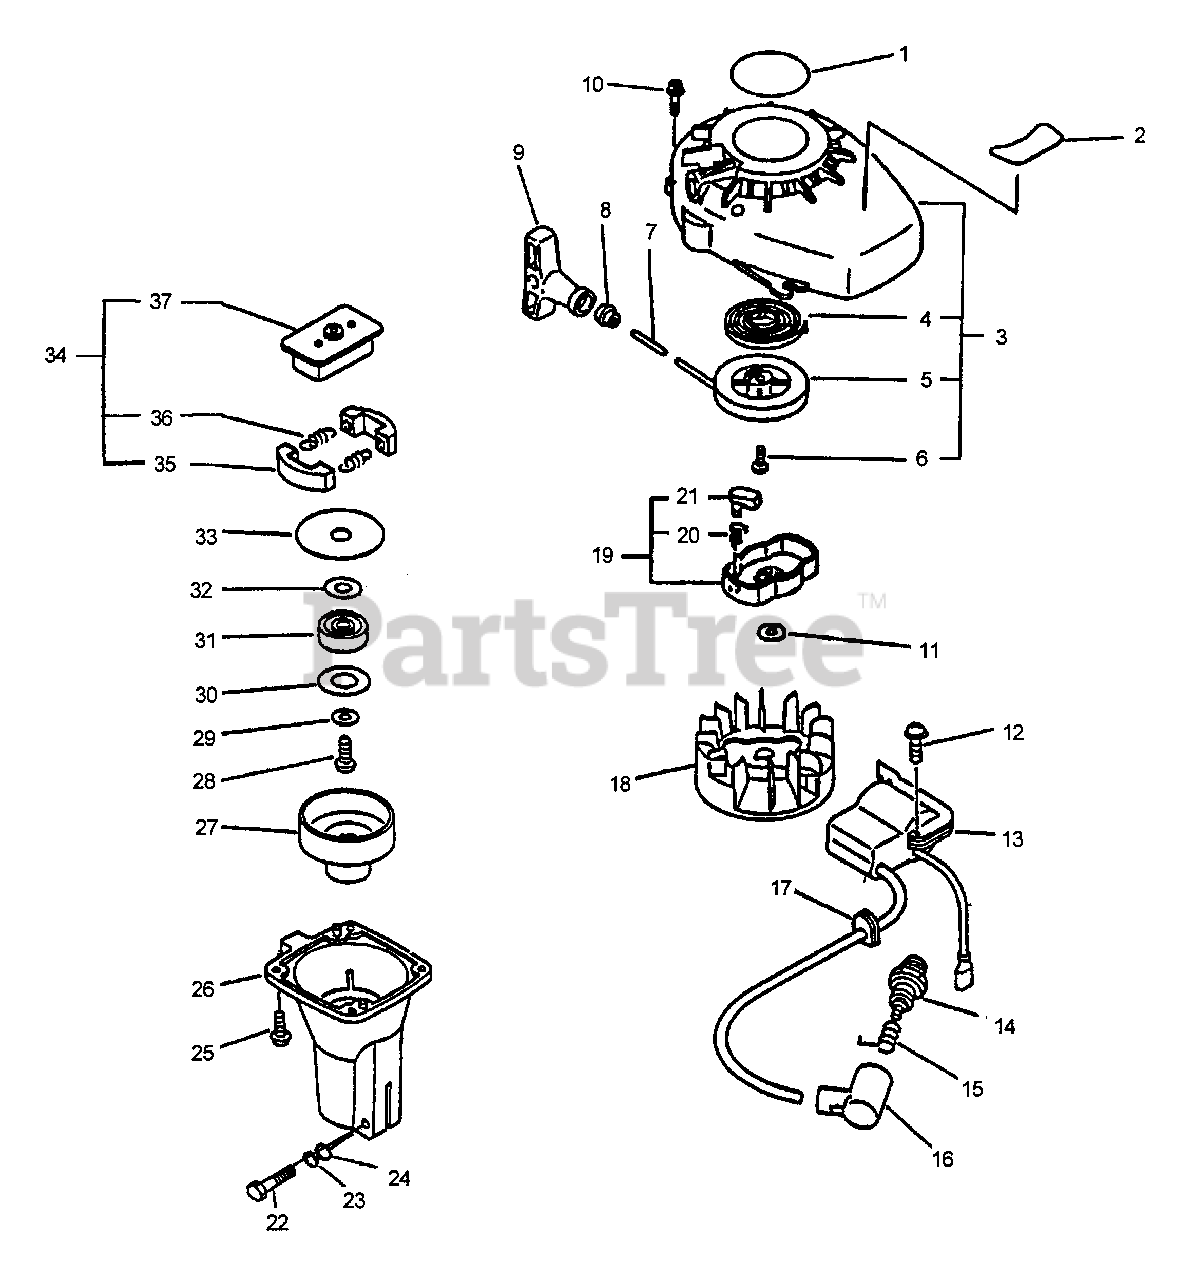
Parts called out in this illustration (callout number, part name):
1	LABEL - ECHO
2	LABEL - MODEL TC-2100 TYPE 1E
3	STARTER ASSY
4	SPRING, REWIND
5	REEL, ROPE
7	RePower BULK ROPE - 200 FEET
8	GUIDE, ROPE
9	GRIP, STARTER
10	SCREW - 4X16
11	LOCKWASHER - 8
12	SCREW - 4X22
13	COIL, IGNITION
14	SPARK PLUG -- BPM-6A
14	SPARK PLUG -- BPM-7Y
15	TERMINAL, SPARK PLUG CAP
16	CAP, SPARK PLUG
18	FLYWHEEL
19	STARTER PAWL ASSY
20	SPRING, RETURN
21	PAWL, STARTER - BLACK
22	BOLT - 5X25
23	LOCKWASHER - 5
24	WASHER - 5
25	SCREW - 4X14
26	CASE, CLUTCH
27	DRUM, CLUTCH
28	SCREW - 6X12
29	WASHER, CLUTCH
30	WASHER, CLUTCH
31	BEARING, BALL - 6000
32	WASHER - 10
33	PLATE, CLUTCH
34	CLUTCH ASSY
35	SHOE, CLUTCH
36	SPRING, CLUTCH
37	HUB, CLUTCH
